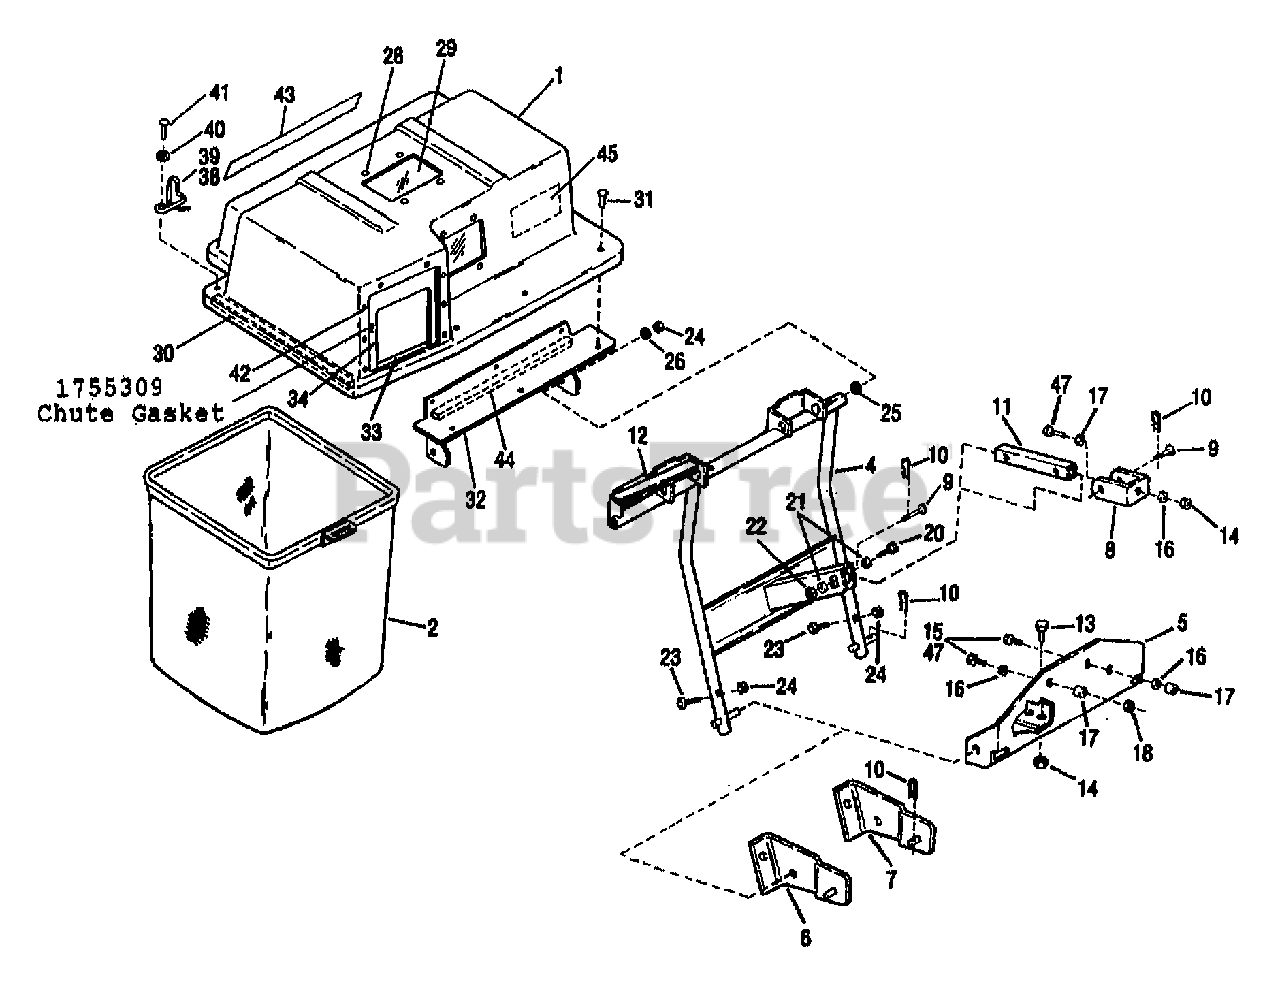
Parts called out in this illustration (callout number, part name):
1	ASSM-CVR GRASS BAG
2	ASSM-GRASS BAG
4	SUPPORT-GRASSBAG
5	PLATE-MOUNTING GRASSBAG
6	ARM-EXTENSION RH
7	ARM-EXTENSION LH
8	BRKT-HITCH
9	PIN-CLEVIS .5X2.0 ZP
10	CLIP-HAIRPIN .07 DIA
11	ADAPTER-ARM
12	SEAL-COVER 9.5"
13	SCR-HH 3/4-10 X 2.00
15	SCR-HH 1/2-13X1.75 G5 ZP
16	WASHER-LK .5
17	SPACER-.75X.531X.89
18	NUT-HEX JAM 1/2-13
20	SCR-HH 1/2-13X2.25 G5 ZP
21	WASHER-1.06X.531X.1 ZP
22	NUT-TOP LOCK 1/2-13 ZP
23	SCR-HH 5/16-18X1.75
24	NUT-TOP/LK 5/16-18 ZP
25	WASHER-.87X.34X.06 NYLON
26	WASHER-FLAT 5/16 SAE
28	WASHER-.505X.22X.05
29	SCREEN
30	COVER-LOCK RH
31	COVER-LOCK LH
32	WASHER-.88X.2X.059
33	RIVET-POP 3/16X1/2
34	RIVET-POP .125
38	RIVET-POP
39	ASSM-COLLAR STOP
40	SUPPORT-TUBE
41	SCR-CARR 5/16-18X1.0 G2 ZP
42	SCR
43	ASSM-FRAME GRASSBAG
44	SEAL-COVER
45	DECAL-INST
47	SCR-HH 1/2-13X1.0 G5 ZP
